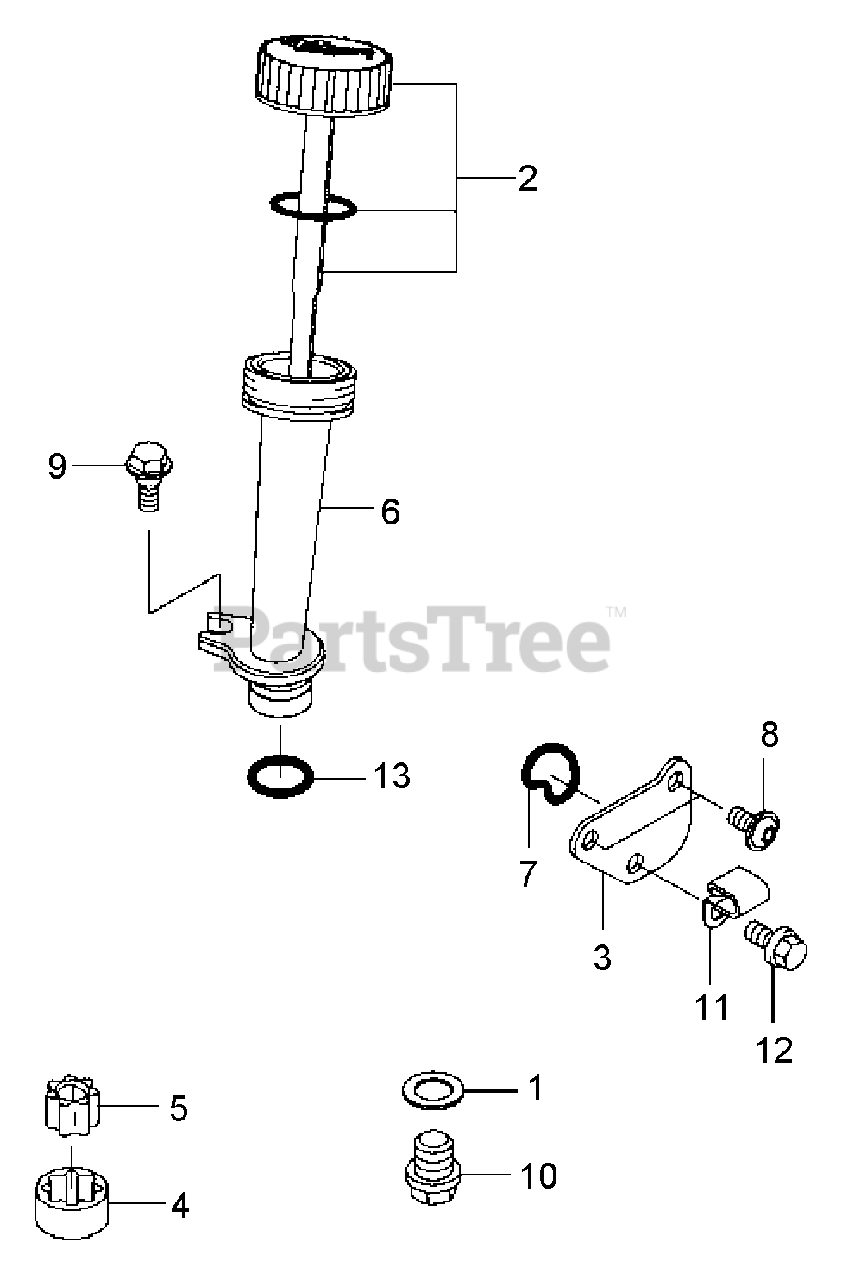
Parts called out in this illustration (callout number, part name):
1	Gasket, 12x19x1.27
2	Dipstick Cap Assy.
3	Oil Filter Cover
4	Oil Pump Rotor (Outer)
5	Oil Pump Rotor (Inner)
6	Filler Tube
8	Bolt, 6x12
12	Flanged Bolt
13	O-Ring, 16mm
